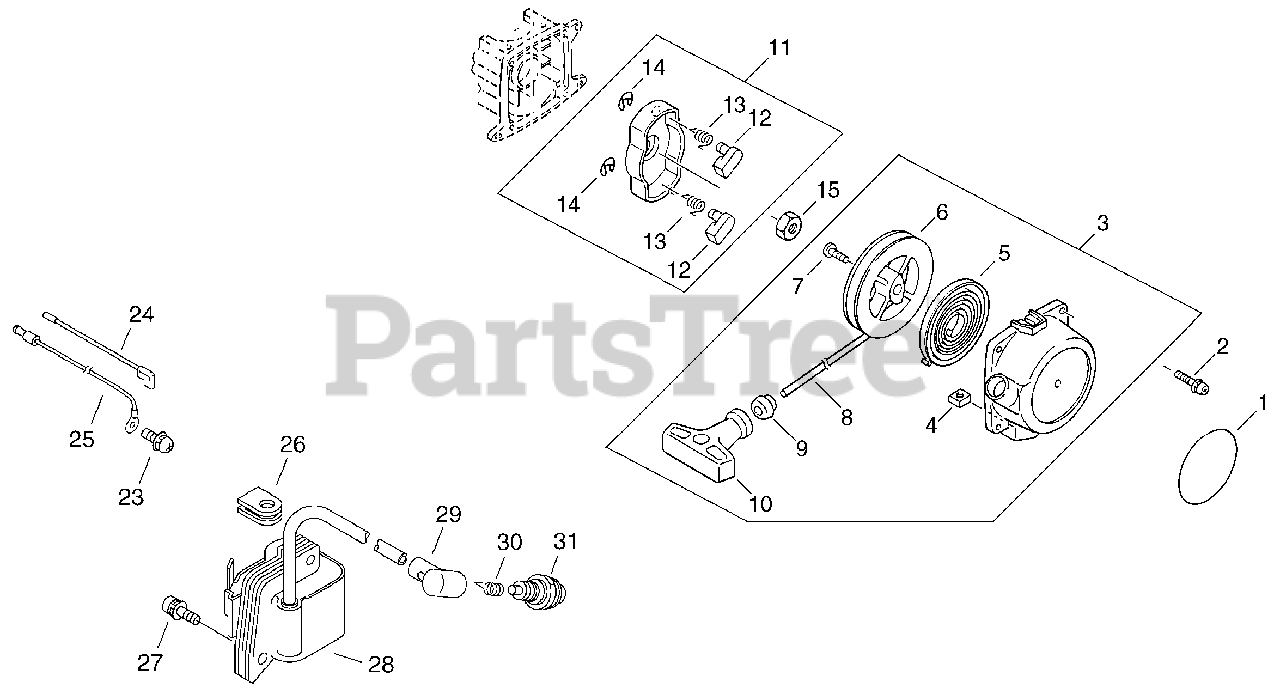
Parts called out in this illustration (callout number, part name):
1	LABEL - ECHO
2	SCREW - 4X14
3	STARTER ASSY
4	NUT - 5 -- SQUARE
5	SPRING, REWIND
6	REEL, ROPE
8	ROPE, STARTER
9	GUIDE, ROPE
10	GRIP, STARTER
11	STARTER PAWL ASSY
12	PAWL, STARTER
13	SPRING, RETURN
14	RING, RETAINING - 4
23	SCREW - 5X10
24	LEAD - IGNITION
25	LEAD - GROUND
27	SCREW - 5X22
28	COIL, IGNITION
29	CAP, SPARK PLUG
30	TERMINAL, SPARK PLUG CAP
31	SPARK PLUG -- BPM-7A
